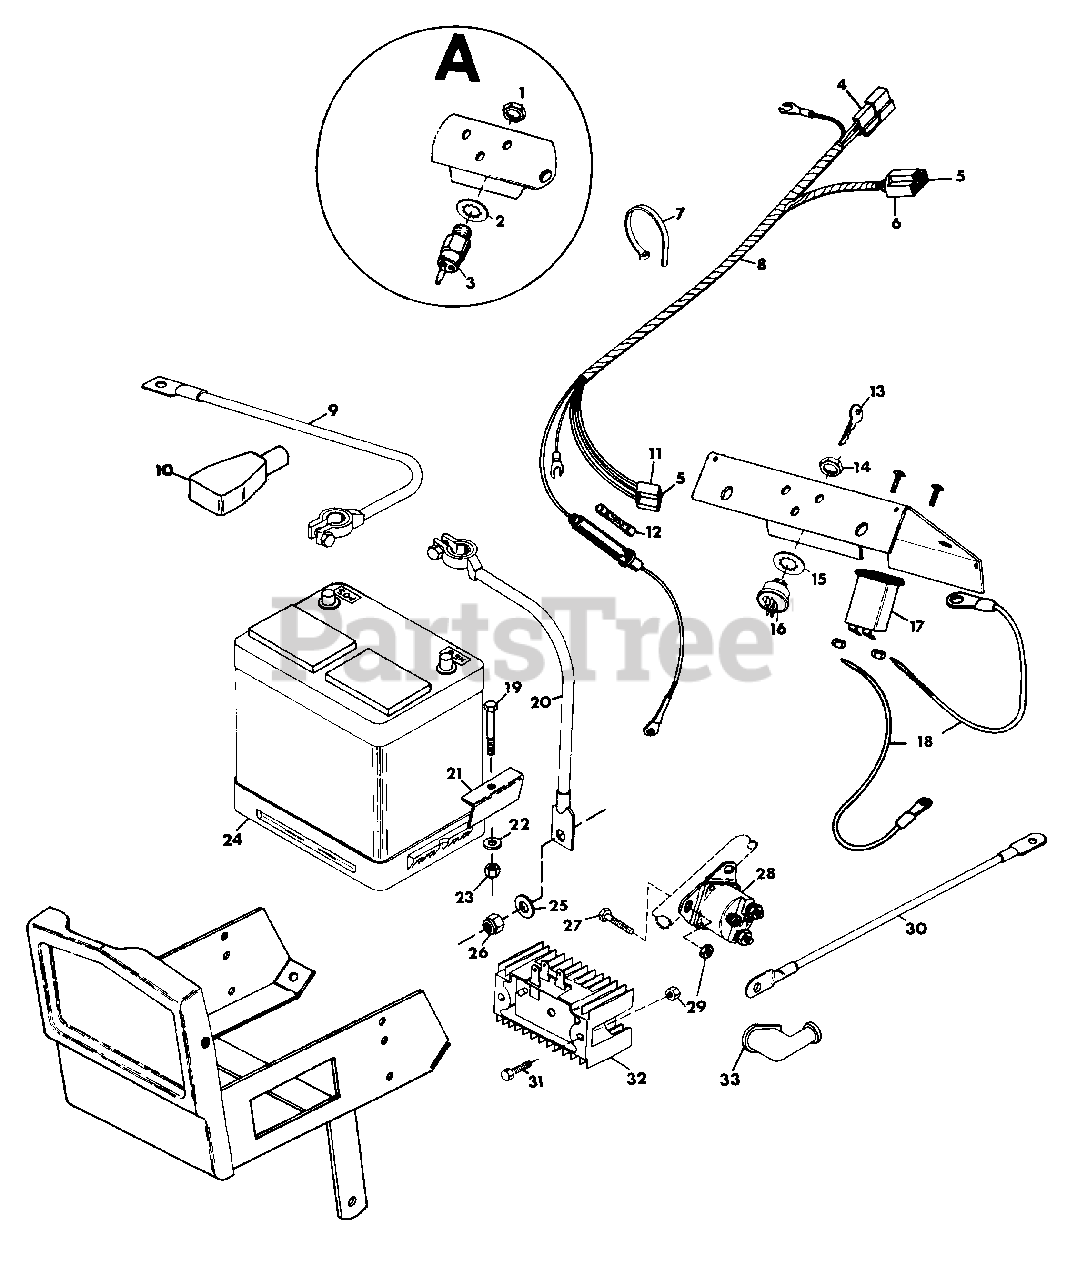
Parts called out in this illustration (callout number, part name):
1	NUT, JAM 5/8-32
2	WASHER, LOCK 5/8 INT. TOOTH
3	SWITCH, IGNITION
4	CONNECTOR(MODEL 5465,5665)
5	TERMINAL(MODEL 5465,5665)
5	TERMINAL(MODEL 5260)
6	CONNECTOR
7	TIE, CABLE
8	HARNESS, WIRING 3 AMP(MODEL 5260)
9	CABLE, POSITIVE BATTERY
10	COVER, BATTERY TERMINAL
11	CONNECTOR(MODEL 5465,5665)
12	FUSE, 30 AMP ACC-30
13	KEY, IGNITION SWITCH
14	NUT, JAM 9/16-24
15	WASHER, LOCK
16	SWITCH, IGNITION
17	HOURMETER
18	WIRE, INSTRUMENT PANEL
19	BOLT, HEX 1/4-20X2.00
20	CABLE, NEGATIVE BATTERY
21	CLAMP
22	WASHER, FLAT .281X.625X.065
23	NUT, LOCK 1/4-20
24	BATTERY, 12 VOLT MAINTENANCE-FREE
25	WASHER, FLAT .406X.812X.065
26	NUT, LOCK 3/8-16
27	BOLT, HEX 1/4-20X1.75
28	SWITCH, MAGNETIC
29	NUT, HEX 1/4-20(MODEL 5260)
29	NUT, HEX 1/4-20(MODEL 5465,5665)
30	CABLE, MAGNETIC SWITCH TO STARTER
31	BOLT, HEX 1/4-20X.75
32	REGULATOR, RECTIFIER
33	BOOT, BATTERY CABLE(MODEL 5260,5665)
